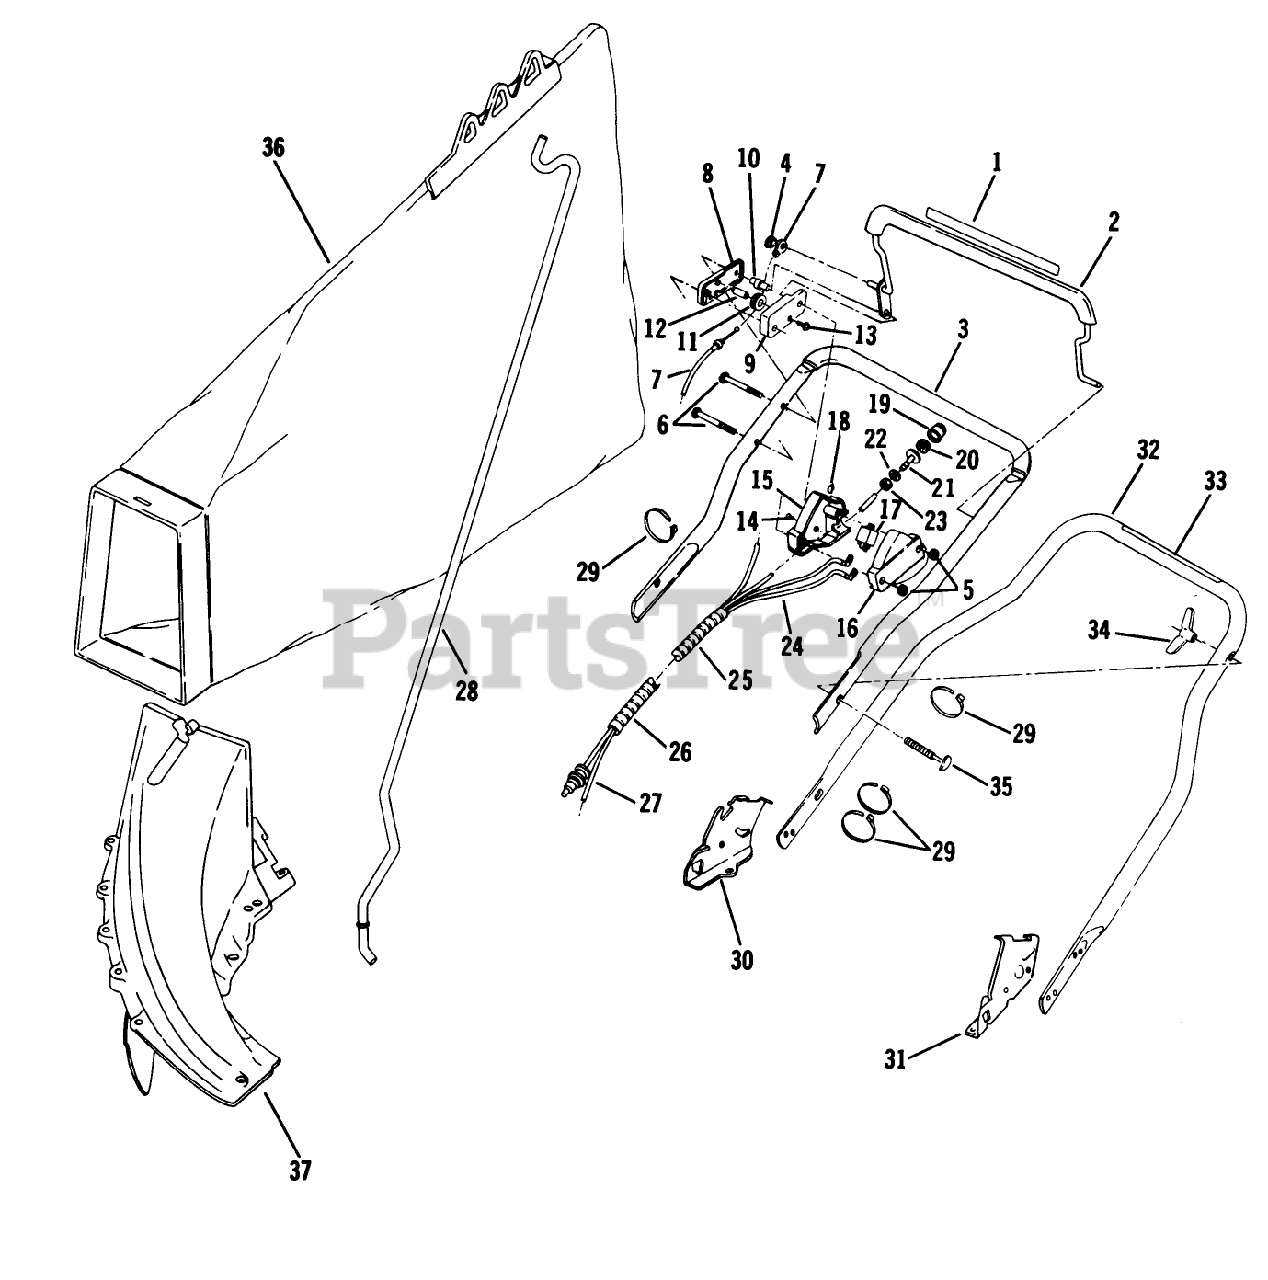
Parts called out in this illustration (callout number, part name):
5	NUT C/LOCK E
10	COLUMN
12	PIN SKF
13	SCREW
20	FILTER S
23	LOCKNUT S
28	ROD GRASSBAG
34	NUT-WING
35	BOLT QUALITY
36	89802 LB WHOLE GOODS
